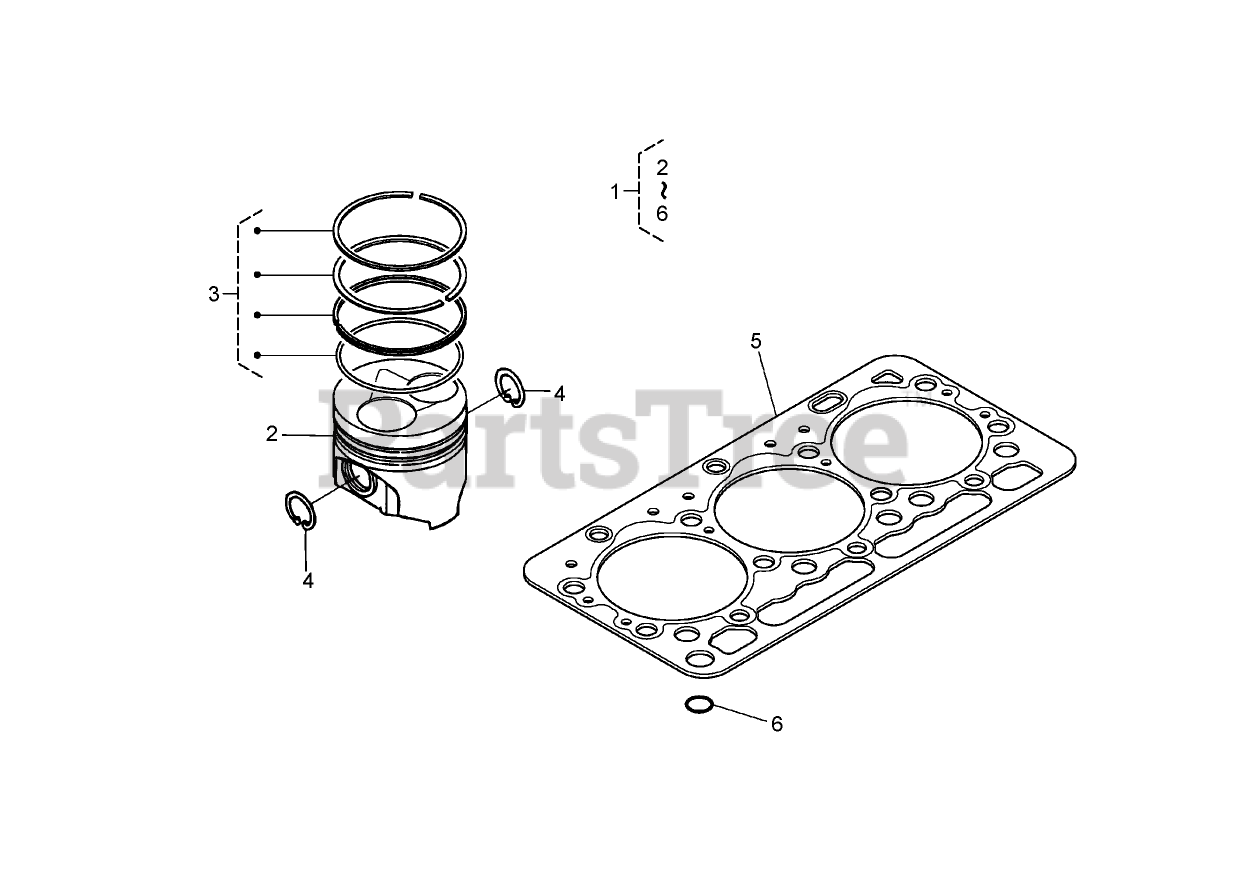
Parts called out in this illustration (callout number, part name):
1	PISTON KIT
2	PISTON
3	PISTON RING ASM (STD)
4	CIRCLIP-INTERNAL
5	GASKET-HEAD, CYLINDER
6	O-RING
